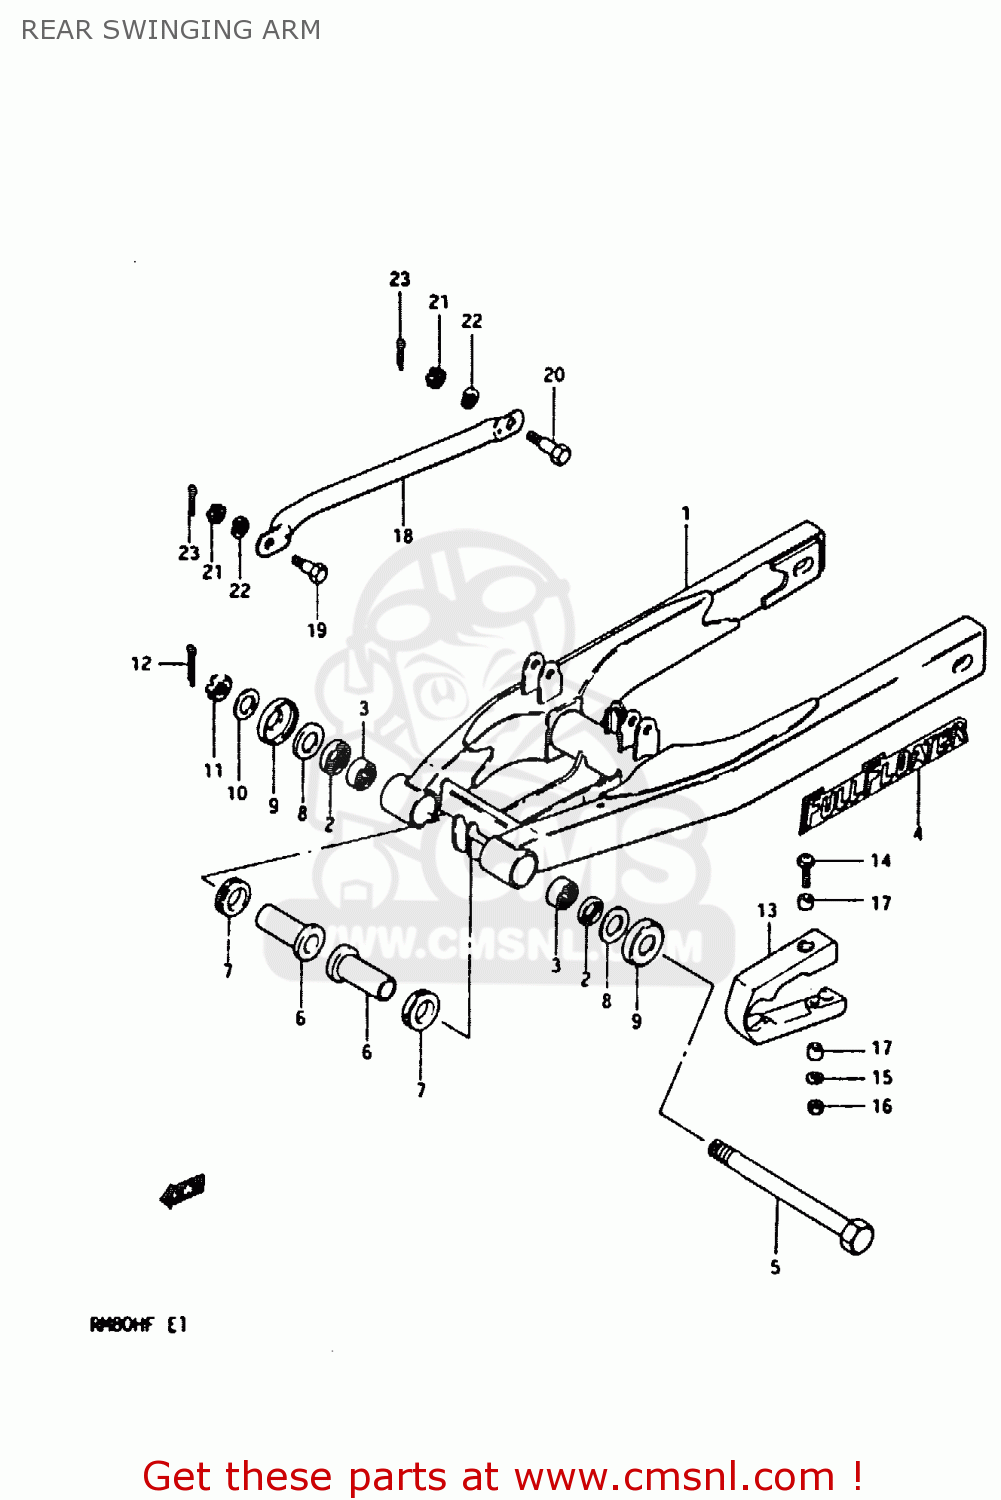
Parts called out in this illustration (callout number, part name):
1	REAR SWINGING ARM SET (GOLD)
2	SEAL,OIL(17X24X3)
3	ROLLER BEARING (17X24X25)
4	EMBLEM
5	SHAFT,REAR SWING ARM
6	SPACER,RR SWGARM PIVOT
7	SEAL,OIL(17X24X5)
8	WASHER
9	COVER,RR SWGARM DUST SEAL
10	WASHER
11	NUT, REAR AXLE
12	COTTER PIN
13	BUFFER,CHAIN TOUCH DEFLECTOR
14	SCREW,CHAIN TOUCH DEFEND
15	WASHER
16	NUT
17	SPACER (5.5X8X4)
18	TORQUC LINK, REAR (GOLD)
19	BOLT(8X22)
20	BOLT(8X21)
21	NUT
22	LOCK WASHER
23	PIN 20X20
